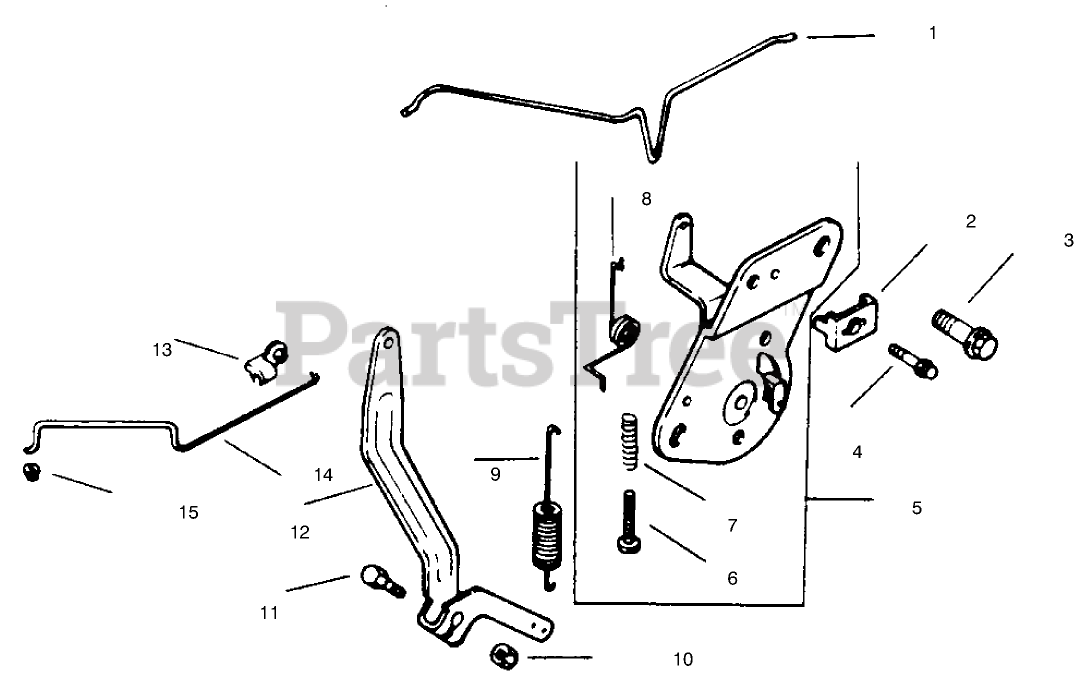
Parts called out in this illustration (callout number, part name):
1	Linkage Choke
2	Clamp
3	Screw
4	Screw
5	Control-Speed ((incl Ref.#6-8)
6	Screw
7	Spring
8	Spring Choke
9	Spring-Governor
10	Nut
11	Screw
12	Lever-Governor
13	Bushing-Linkage
14	Linkage-Throttle
15	Bushing-Linkage
